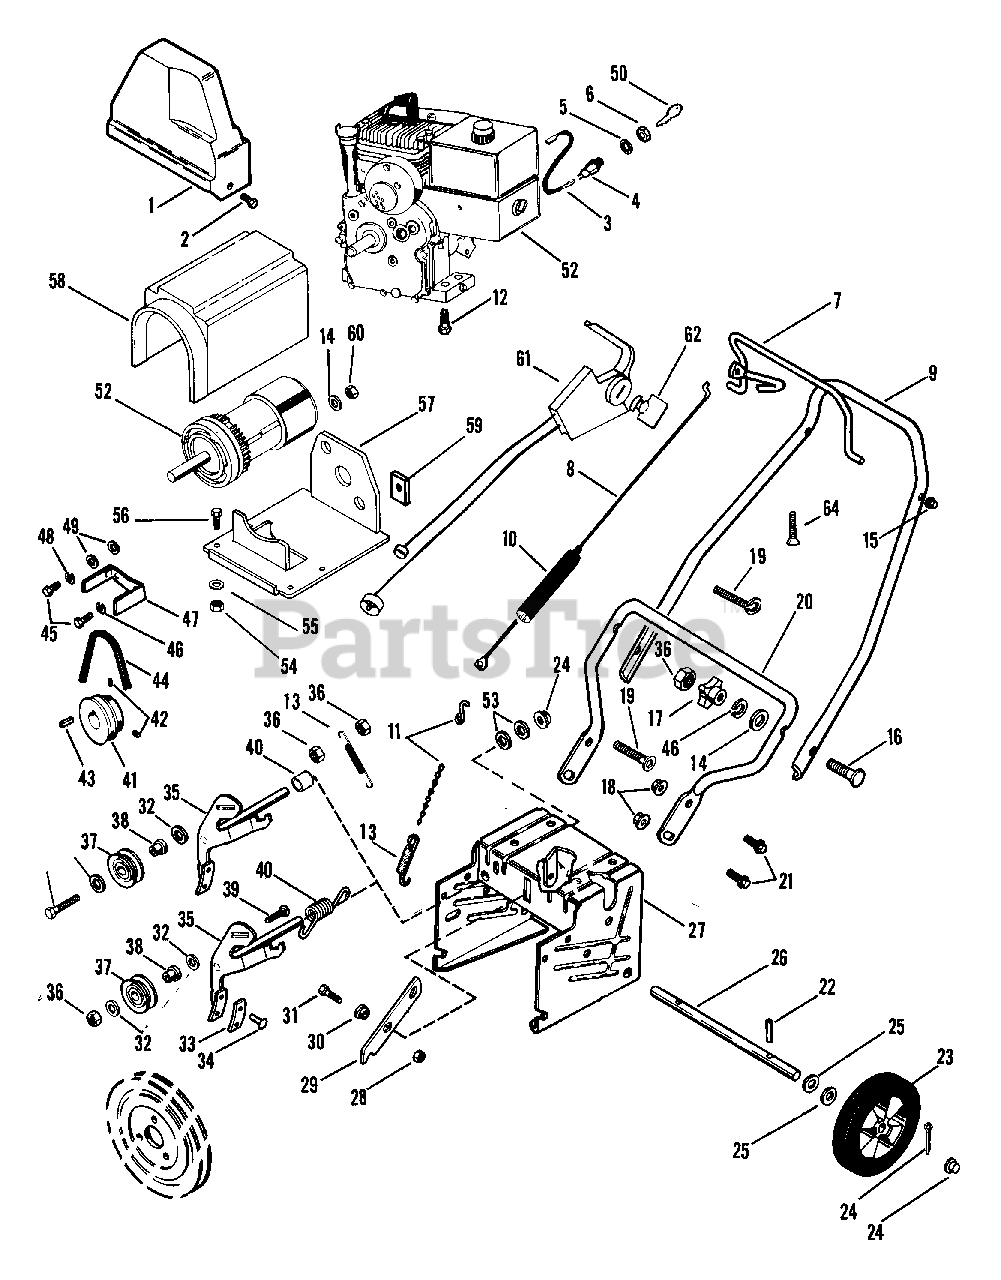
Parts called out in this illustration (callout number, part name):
1	BELT COVER
2	SCR-TAP .250-20X.37 HWH PL TR
3	WIRE
4	SWITCH
5	WSHR-LK-INT .625X.045 PL
6	NUT .625-32 ALUM
7	BAIL
8	CABLE
9	UPPER HANDLEBAR
10	COVER
11	CHAIN & CONNECTOR
12	SCR-TAP .375-16X1.0 HWH PL TR
13	SG-TENS .072X.51X5.31 WLD 25
13	SG-TENS .091X.56X6.12 WLD 40
13	SG-TENS .091X.56X4.25 WLD 40
14	WSHR-FL-STL .323X.625X.062 PL
15	NUT-PUSH .312 DIA. PAL
16	BLT-CRVD-HD .31-18X3.0 PL
17	KNOB 5/16-18UNC THREAD
18	NUT-FLG. .312-18 PL
19	TIE DOWN
20	LOWER HANDLEBAR
21	BLT-SERHFWH .31-18X.62 PL
22	PIN-ROLL .125X.75
24	CAP, .50 ROD YWZC
24	PIN-COTR .12X1.0 PL
25	WSHR-FL-STL .511X1.441X.125 PL
28	NUT-LK-CTR .250-20 PL
29	ARM
30	BSHG-FLG .265X.437X.250X.750
31	BLT-HEX .25-20X.63 PL GR2
32	WSHR-FL-STL .38X.875X.083 PL
33	BRAKE LINING
34	RVT-TBLR .187X.437 RH ST PL
35	BRAKE CLUTCH ARM W/LINING
35	IDLER ARM
36	NUT-LK .312-18 GR A PL
37	IDLER
38	SPCR, BRG .315X.50X.688X.281
39	BLT-HEX .31-18X1.75 PL GR2
39	BLT-RDHDSQNK .31-18X1.38SHT PL
40	SG-TORS .148X1.0X1.53
40	SPACER .520X.640X1.375
41	ENGINE SHEAVE
42	SCR-SET .32-18X.38 SKHCUPNL OH
43	KEY-SQ .188X1.0X.188 SAE 8630
44	V-BELT, 4L-COGGED
45	BLT-HEX .31-24X.75 PL GR5
46	WSHR-LK .312X.097 PL HVY
47	BELT FINGER
48	WSHR-LK .313X.093 MED HICLR
49	WSHR-FL-STL .380X.875X.179 PL
50	KEYS
52	2.7 HP LAUSON ENGINE W/O CAM
52	2.7 HP TEC ENGINE
52	MOTOR-ELEC. B&S SERIES 748002
52	ENGINE-HSK 30 TEC
52	5HP TEC ENGINE
52	ENGINE-HSSK 50 TEC NO PTO
53	WSHR-FL-STL .531X1.062X.095 PL
54	NUT-LK .312-18 GR A PL
55	WSHR-FL-STL .328X.875X.062 PL
56	BLT-HEX .31-18X.63 PL GR 2
57	MOTOR MOUNTING BRACKET
58	SHROUD
59	STRAIN RELIEF
60	NUT-EXTENDED 10-24 BRIGGS
61	CONTROL BOX
62	KEY
63	INSULATOR
64	SCR-MCH 10-24X1.50 CROVCNTRS
